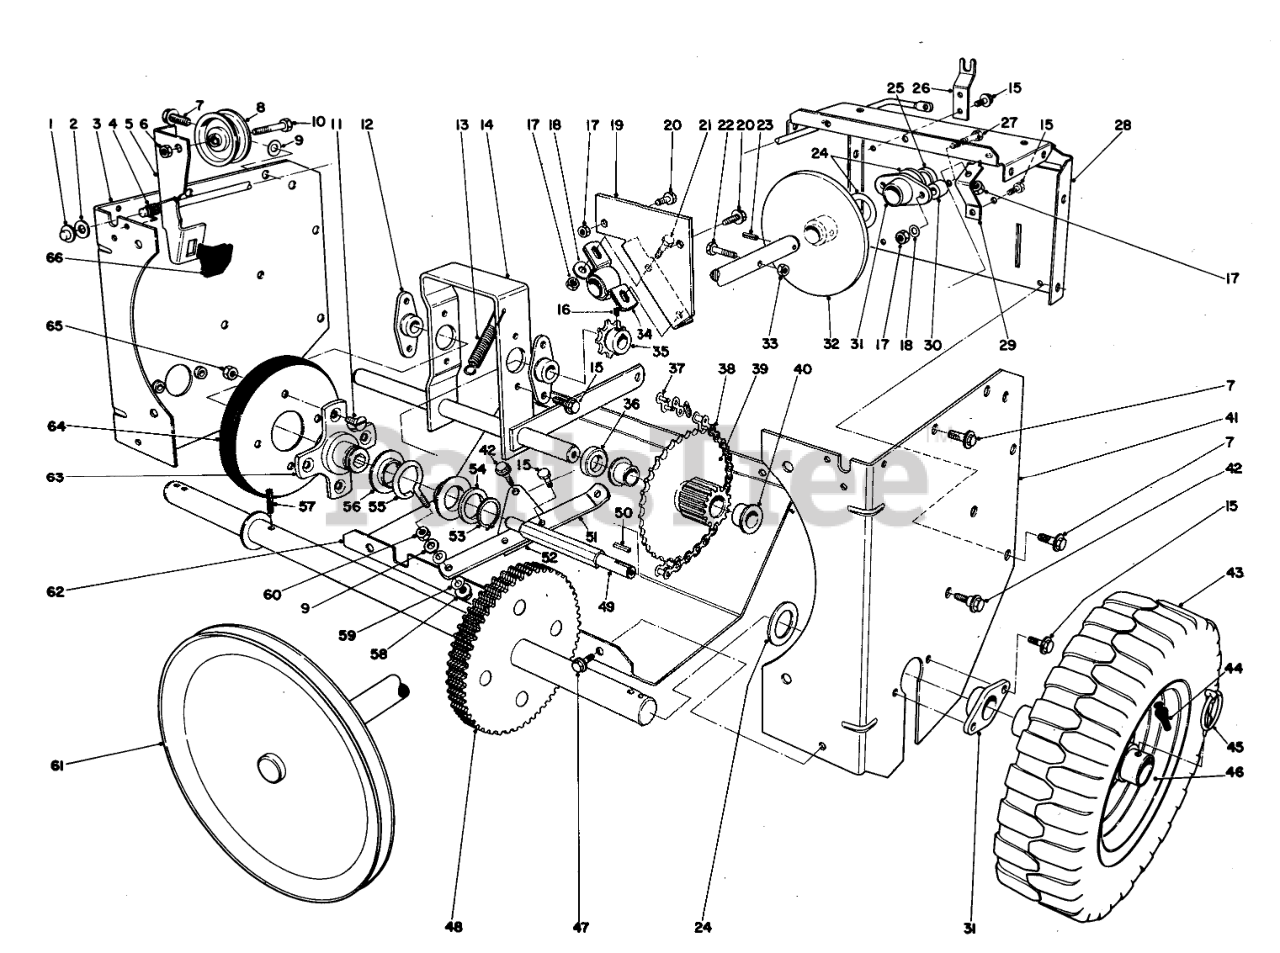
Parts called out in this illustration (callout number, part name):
1	PUSH NUT
2	WASHER-FLAT
3	RH TRACT SIDE PLT R
4	TORSION CLUTCH SPRING
5	Clutch Rod (Incl. Ref. #66)
6	NUT-LOCK, NI
7	SCREW-HHFTF
8	PULLEY-IDLER
9	WASHER-FLAT
10	SCREW-HH
11	5/16-18X5/8 FLT HD MS
12	BEARING-WHEEL, FRICTION
13	TENSION SPRING
14	PIVOT SHAFT WA B
15	SCREW-HWHTF
16	SCREW-HSH
17	NUT-LOCK, NI
18	WASHER-PLAIN
19	SHAFT SUPT BRKT B
20	SCREW-HH
21	SCREW-HH
22	SCREW-HH
23	PIN-ROLL, SLOTTED
24	WASHER
25	DRIVE SHAFT SPACER
26	CLUTCH ROD SUPPORT
27	SCREW-HH
28	CENTER FRAME R
29	PIVOT BRACKET
30	BRG STANDOFF
31	AXLE BEARING
32	FRICTION PLT WA
33	NUT-LOCK, CONE
34	PILLOW BLOCK BRG
35	SPROCKET
36	COSHAFT SPACER
37	LINK-CONNECTING
38	ROLLER-CHAIN
39	Gear & Bushing (Incl. Ref. #40)
40	BUSHING
41	LH TRACT SIDE PLT R
42	SHOULDER SCREW
43	Tire
44	STEM-VALVE
45	PIN-LYNCH
46	Wheel
47	SCREW-HWH
48	AXLE & GEAR WA
49	FRICTION WHL SHAFT
51	SHIFT LINKAGE
52	PIVOT PLATE
53	RING-RETAINING
54	WASHER-THRUST
55	SLIDER RING COLLAR
56	SLIDER RING
57	PIN-ROLL, SLOTTED
58	NUT-LOCK, FLANGE
59	WASHER-SPRING
60	NUT-LOCK
61	PULLEY/SHFT WA
62	LOWER SHIELD R
63	TRACTION DISC HUB
64	FRICTION WHEEL
65	NUT-LOCK, NI
66	Brake Pad
